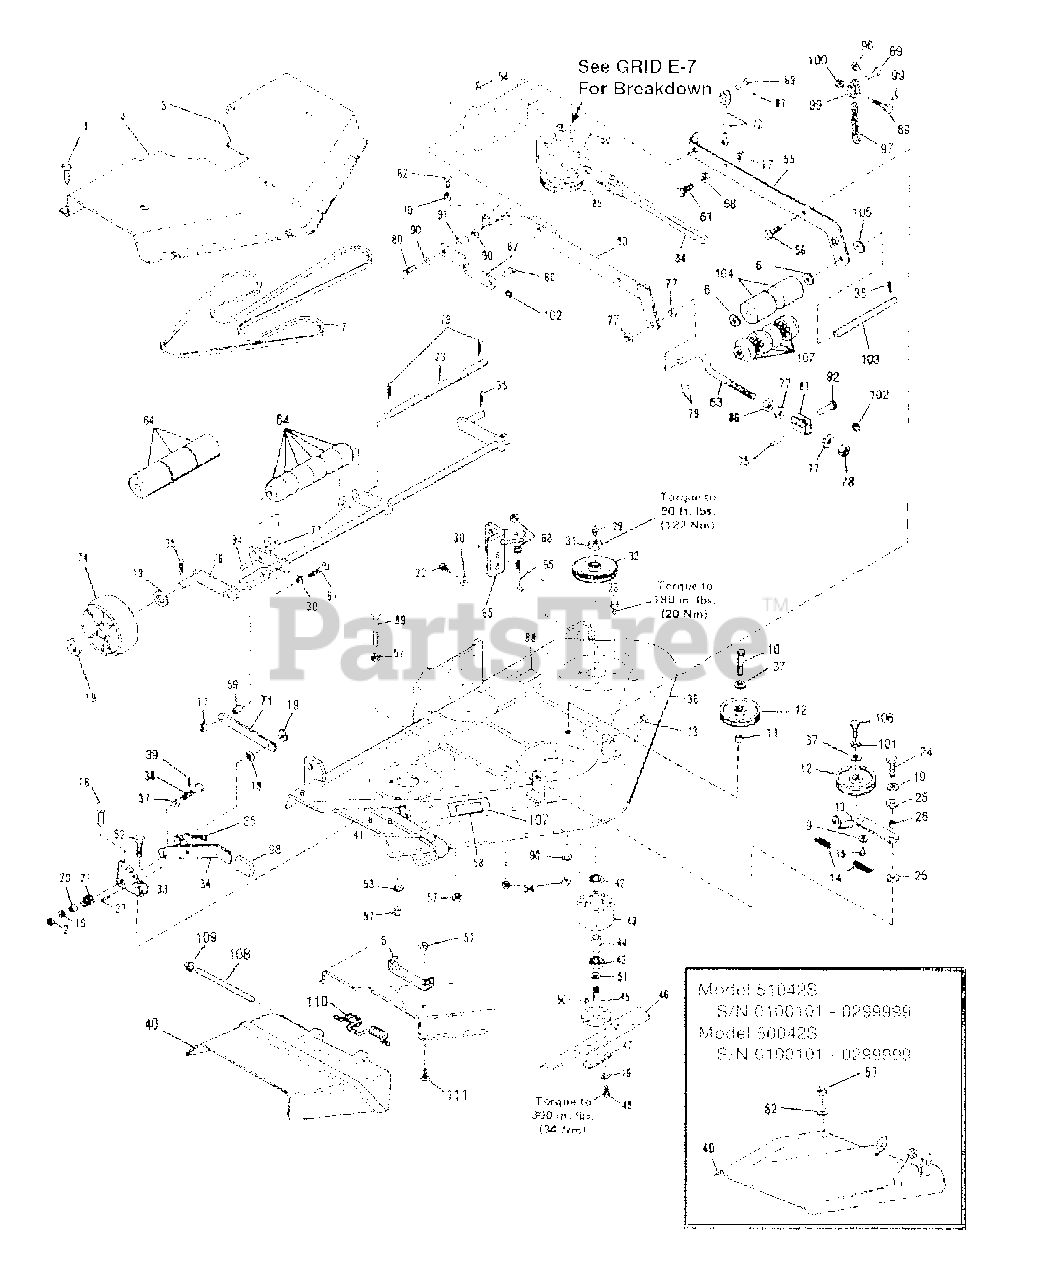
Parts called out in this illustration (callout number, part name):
1	Self Driving Screw, 10-24 x 1/2
2	Lock Nut, 1/2-13
3	Belt Cover, LH
4	Belt Cover, RH
5	Hinge Bracket
6	Flat Washer, 5/8
7	V-Belt (105")
9	Lockwasher, 10
10	Hex Screw 1/2-13 x 2
11	Spacer
12	Idler Pulley
13	Idler Arm
14	Extension Spring
15	Wear Button
16	Lockwasher, 3/8
17	Lock Nut, 3/8-16
18	Carriage Bolt, 5/16-18 x 3/4
19	Flat Washer, 1/2
20	Spacer
21	Spring
22	Hex Screw 3/8-16 x 1
23	Axle Roller
24	Capscrew, 1/2-13 x 1-1/2
25	Thrust Washer
26	Bearing Sleeve
27	Drive Pin, 5/16-18 x 3/4
28	Flange Screw, 5/16-18 x 3/4
29	Grease Fitting
30	Flat Washer 3/8
31	Locknut, 3/4-16
32	Blade Sheave
33	Quadrant
34	Handle Assembly
35	Cotter Pin, 1/8 x 1
36	Mower Base Ass'y
37	Flat Washer, 1/2
38	Special Screw
39	Roll Pin, 3/16 x 7/8
40	Discharge Chute
41	Decal, Cutting Line
42	Ball Bearing
43	Spindle Housing
45	Shaft Assembly
46	Blade
47	Plate
49	Capscrew, 3/8-24 x 1
50	Woodruff Key, 3/16 x 3/4
51	Flat Washer, Special
52	Hex Capscrew, 5/16-18 x 3/4
53	Flat Washer, 5/16
54	Lock Nut, 1/2-13
55	Support Assembly LH
56	Flange Screw 3/8-16 x 1
57	Top Locknut, 5/16-18
58	Decal, Mower
59	Spacer
60	Clevis Pin
61	Capscrew, 3/8-16 x 1-1/2
62	Fl. Screw 3/8-16 x 2
63	Hitch Link
64	Roller
65	Shaft Support Assembly
67	Drag Link
68	Jam Nut 3/8-16
69	Clevis Pin
70	Hex Nut, 3/8-16
71	Link, Connecting
72	Lift Cable
73	Flange Nut 3/8-16
74	Gage Wheel
75	Roll Pin 3/16 x 1-1/8
76	Pivot Shaft Assembly
77	Flat Washer
78	Hex Nut 3/4-10
79	Cotter Pin, 1/8 x 1-1/4
80	Hex Screw 1/2-13 x 1-3/4
81	Hitch Bracket
82	Flat Washer
83	Mower Hanger, RH
84	Drive Assembly
85	Roll Pin, 3/16 x 1-1/2
86	Hex Nut 3/4-10
87	Cotter Spring
88	Belt Drive Decal
89	Hex Screw 5/16-18 x 1-1/4
90	Flat Washer, 1/2
91	Spacer
92	Clevis Pin
94	Drive Pin, 1/8 x 3/4
96	Circle Cotter
97	Chain
98	Grip
99	Lock Nut 5/16-18
100	Clevis
101	Lock Washer 1/2
102	Ring Cotter
103	Roller Shaft
104	Roller
105	Flat Washer
106	Hex Screw 1/2-13 x 1-1/4
107	Roller
109	Push Nut
110	Torsion Spring
111	Carriage Bolt .312-18 x .62
